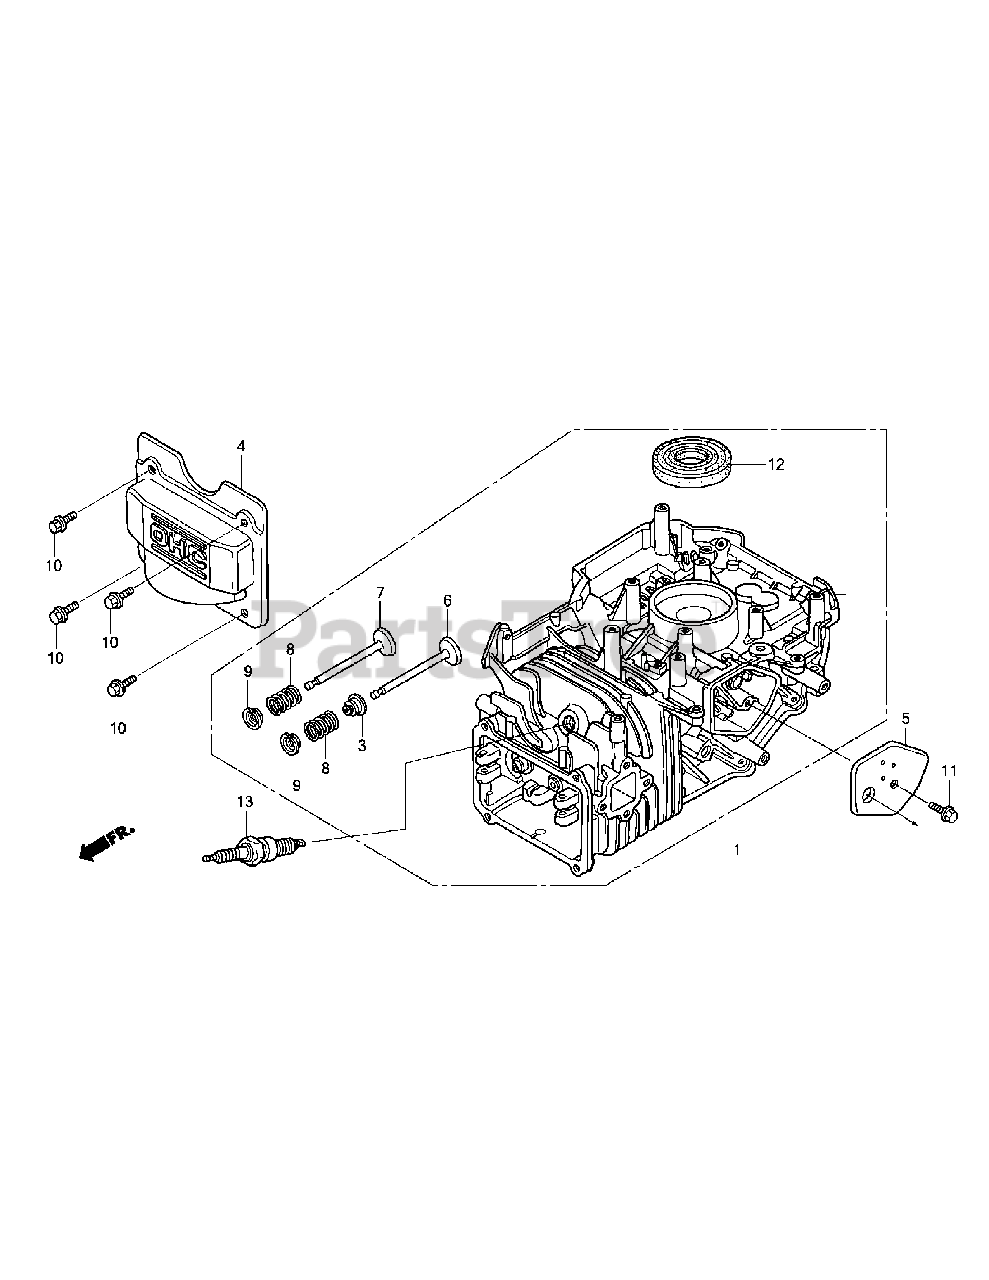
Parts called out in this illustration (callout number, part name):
1	Cylinder Assy.
3	Seal, Valve Stem
4	See Part Details - Cover, Head
5	Cover, Breather
6	Pri; Valve, In. (Rocknel)
7	Valve, Ex.
8	Spring, Valve
9	Retainer, Valve Spring
10	Bolt, Flange (6x12) (Ct200)
11	Bolt, Flange (6x14) (Ct200)
12	Oil Seal (25.4x62x6)
13	Spark Plug (Bpr6es) (NGK)
